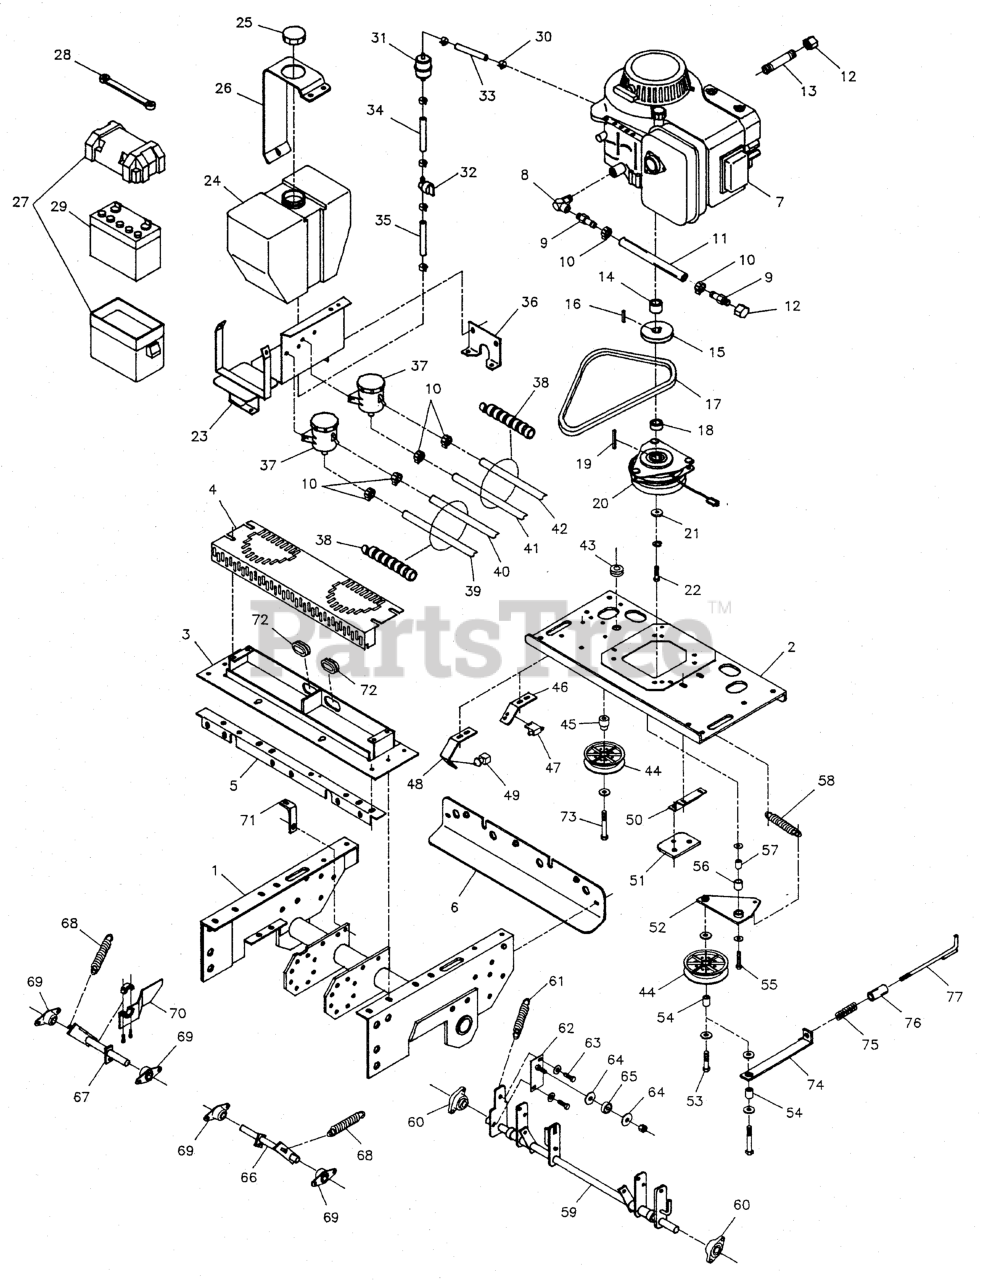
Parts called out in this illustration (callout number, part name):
1	ENGINE DECK
2	Engine Deck Plate
3	FAN SHROUD
4	FAN COVER
5	SUPPORT, Engine Deck
6	Engine Deck Back Plate
8	90 Degree Fitting
9	FITTING, 3/8NPT-1/2" Hose, Straight
10	CLAMP, #6 Hose
11	1/2" Hose, 18" Long
12	CAP, 3/8 NPT
13	Pipe Nipple
14	SPACER, 1.00 X 1.50 X 1.12
15	PULLEY, Crankshaft
16	KEY, 1/4" SQ. X 1-1/4
18	WASHER, 1" SAE
19	KEY, 1/4 SQ. X 1
20	CLUTCH, Electric, 1" Shaft
21	SPACER, .45 x 1.62 x .37
22	BOLT, M10 x 70MM
23	Gas Tank Mount (Electric)
23	Gas Tank Mount (Manual)
24	FUEL TANK, 4 Gallon
25	CAP, Fuel Tank
26	FUEL TANK STRAP
27	BATTERY BOX, W/ DRAIN HOLE
28	RUBBER STRAP
29	BATTERY, Lawn & Garden, 12V (BCIU1, 340 CCA)
30	CLAMP, Hose
31	FUEL FILTER
32	VALVE, Fuel Shut-Off
33	1/4" Fuel Line, 3" Long
33	1/4" Fuel Line, 4" Long
33	Fuel Line
34	1/4" Fuel Line, 3" Long
34	1/4" Fuel Line, 7" Long
34	1/4" Fuel Line, 4" Long
35	1/4" Fuel Line, 11" Long
35	HOSE, 1/4" FUEL, 9.00"
35	1/4" Fuel Line, 12" Long
36	Gas Tank Mount Leg
37	RESERVOIR, Hydraulic
38	Protective Coil, 10" Long
39	HOSE, 3/8" PUSH-LOCK, 35.00"
40	HOSE, 3/8" PUSH-LOCK, 43.00"
41	HOSE, 3/8 PUSH-LOCK, 26.00
42	HOSE, 3/8" PUSH-LOCK, 37.00"
43	GROMMET, 1/2"
44	PULLEY, Backside Idler
45	INSERT, Bearing Shoulder
46	MOUNT, Switch
47	SWITCH, Plunger, NO
47	SWITCH, PLUNGER, N.C.
48	Switch Mount Plate
49	Parking Brake Switch
50	ANCHOR, Clutch
51	CLUTCH ANCHOR PAD
52	ASSM, MOUNT, GROUND DRIVE IDLER - RED
53	BOLT, 1/2-20 X 1-1/2, GD5 CZ
54	INSERT, Bearing
55	BOLT, 5/16-18 x 1-1/2
56	BUSHING, Brass
57	SPACER, .32 x .75 x 1.06
58	SPRING, Extension
59	Control Shaft
60	BEARING, Flange
61	SPRING, Extension
62	Lock Mount Plate
63	BOLT, 1/4-20 x 3/4
64	WASHER, 3/8" Fender
65	Bearing
66	SHAFT, Brake, Left
67	Brake Shaft Right
68	SPRING, Extension
69	BEARING, Flange
70	Neutral Lock Plate
71	Deck Support
72	GROMMET, 1-1/4"
73	BOLT, 1/2-20 X 2-1/2" GD5 CZ
74	Belt Disengagement Link
75	SPRING, Compression
76	5/8" Hose, 1-5/16" Long
77	Belt Disengagement Rod
